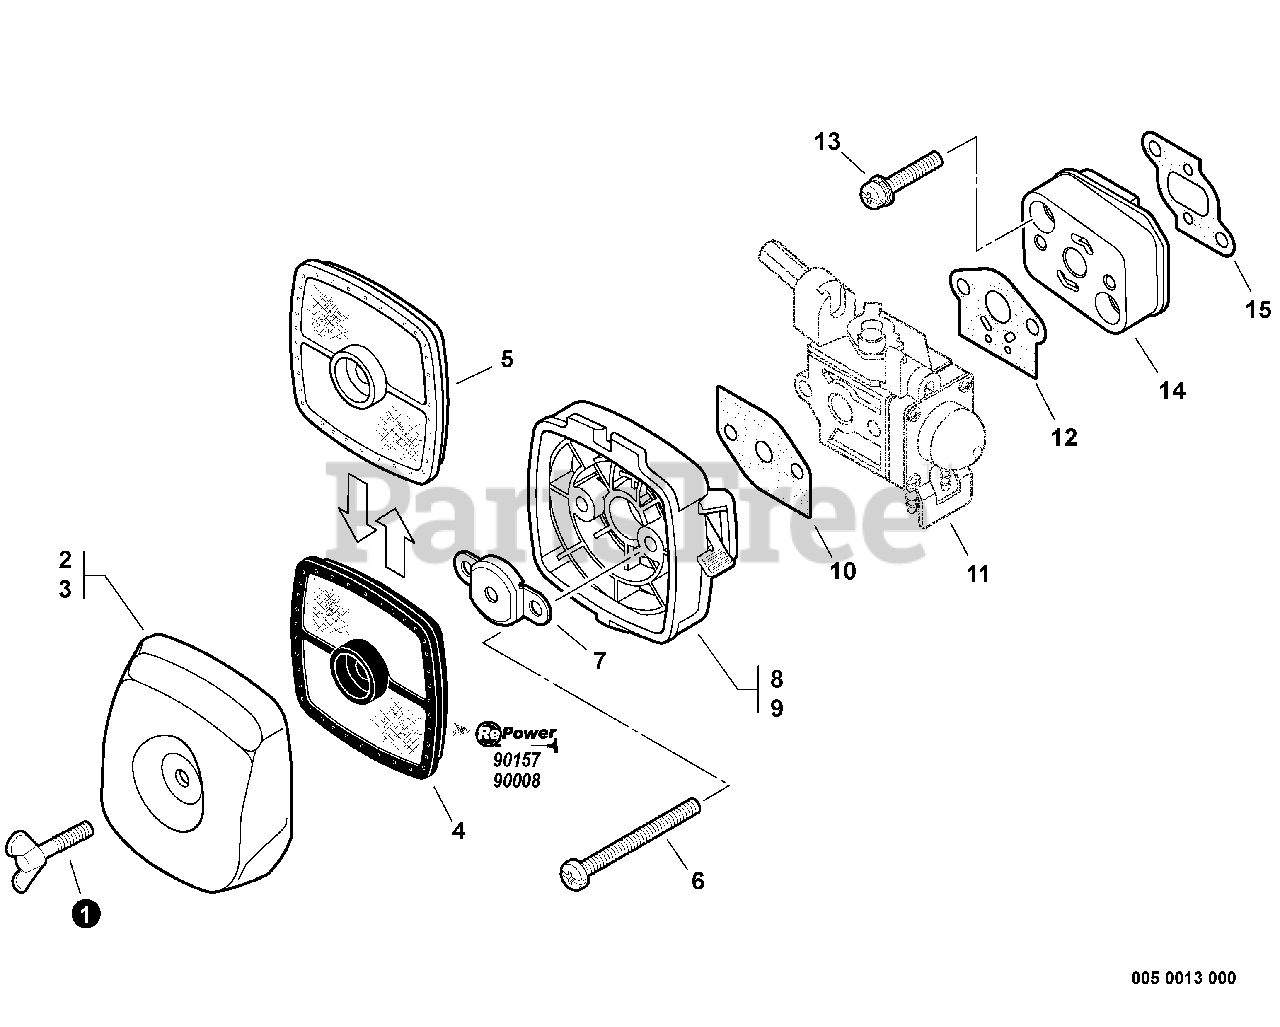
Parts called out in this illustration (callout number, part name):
1	THUMBSCREW
2	COVER, AIR FILTER - GRAY
3	COVER, AIR FILTER - BLACK
4	FILTER, AIR - DOUBLE LAYER
5	FILTER, AIR - SINGLE LAYER
6	SCREW - 5X60
7	PLATE, PREVENT
8	CASE, AIR FILTER - GRAY
9	CASE, AIR FILTER - BLACK
10	GASKET, INTAKE
11	CARBURETOR
12	GASKET, INTAKE
13	SCREW - 5X25
14	INSULATOR, INTAKE
15	GASKET, INTAKE
16	RePower TUNE-UP KIT
17	RePower FILTER KIT
